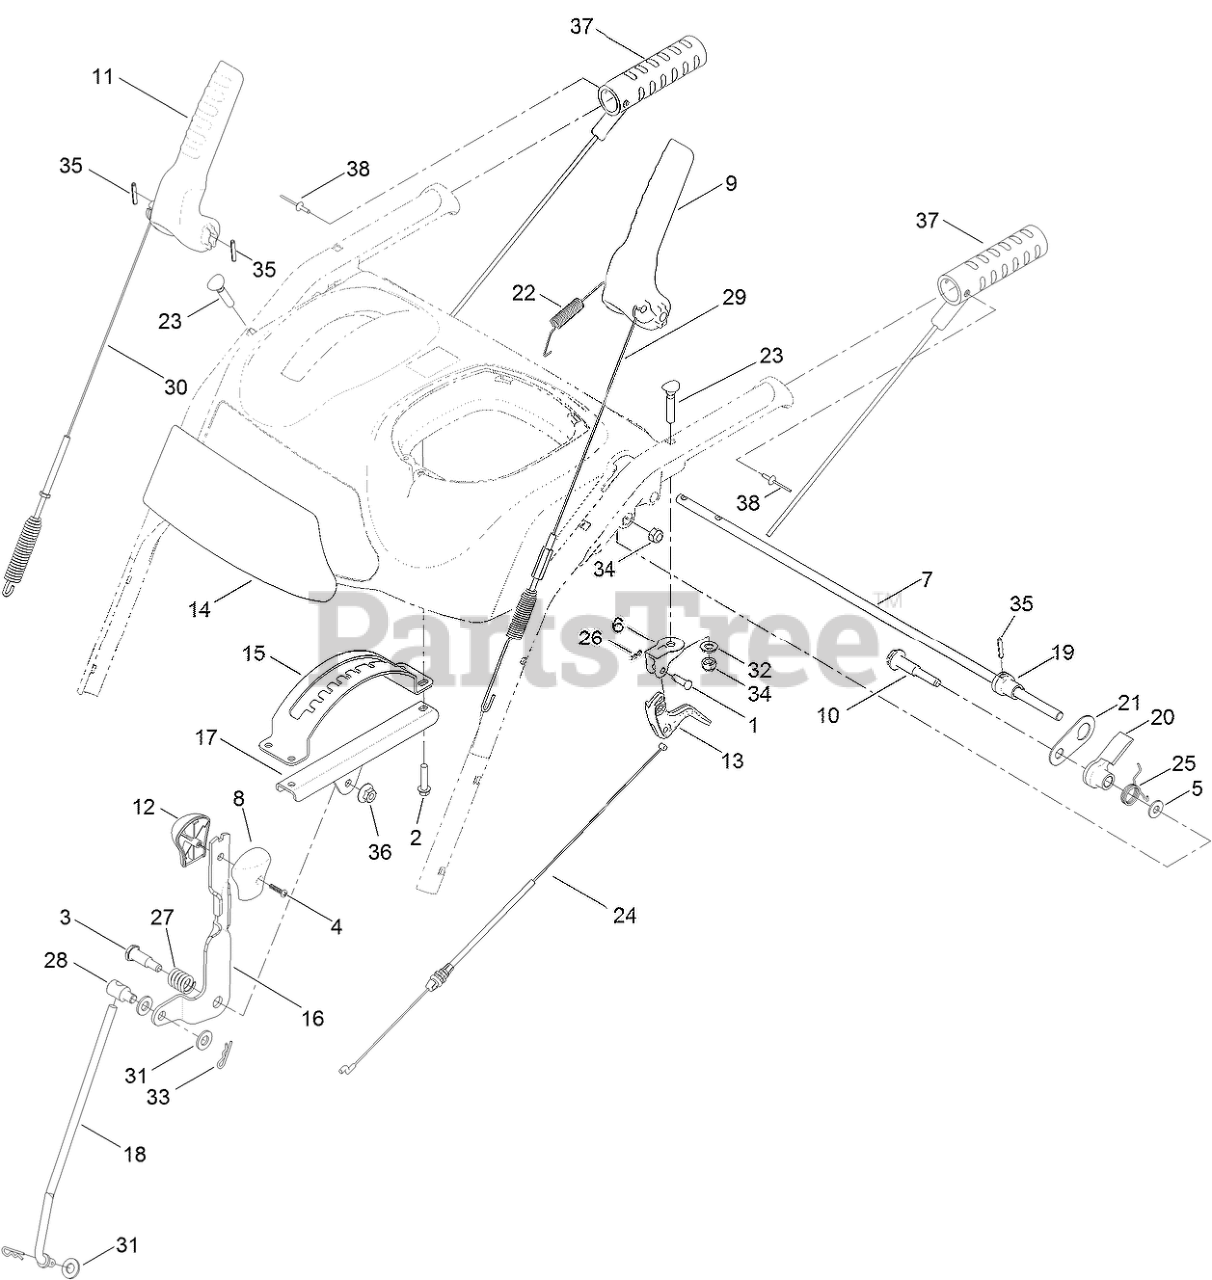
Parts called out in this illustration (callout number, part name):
1	PIN-CLEVIS
2	SCREW-PLASTITE
3	SCREW-SHOULDER
4	SCREW-PPH
5	WASHER-FLAT
6	MOUNT-CLUTCH, LEVER
7	ROD-LOCKOUT
8	KNOB-SHIFT, LH
9	LEVER-TRACTION
10	SCREW-SHOULDER
11	LEVER-AUGER
12	KNOB-SHIFT, RH
13	LEVER-CLUTCH
14	DECAL-CONTROL PANEL
15	GUIDE-SELECTOR, SPEED
16	SELECTOR-SPEED
17	BRACKET-SELECTOR, SPEED
18	ROD-SHIFT
19	CAM-LOCKOUT
20	LATCH-LOCKOUT
21	LINK-LOCKOUT
22	SPRING-TENSION
23	SCREW-HANDLE
24	CABLE-CLUTCH
25	SPRING-TORSION
26	PIN-HAIR
27	SPRING-COMPRESSION
28	TRUNNION-ROD
29	CABLE-TRACTION
30	CABLE-AUGER
31	WASHER-FLAT
32	WASHER-FLAT
33	PIN-COTTER
34	NUT-LOCK, NI
35	PIN-SPRING
36	NUT-HF
37	GRIP-HEATED
38	RIVET-POP
